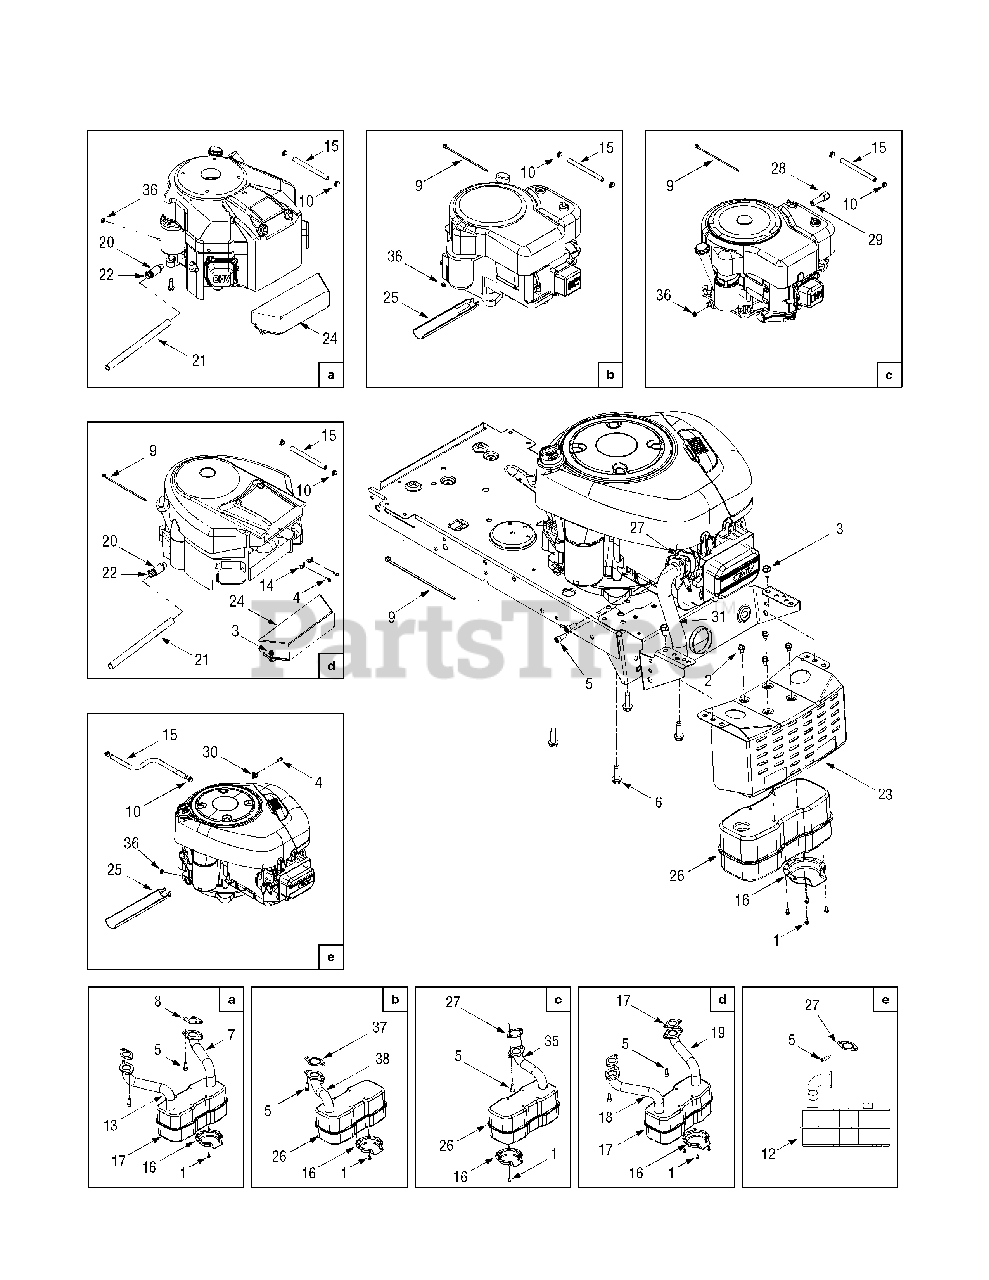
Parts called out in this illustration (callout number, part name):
1	Screw, #8-32, .375
2	Self-tapping Screw, 1/4-14, .625
3	Self-tapping Screw, 5/16-12, .75
4	Screw, #10-32, .625
5	Socket Cap Screw, 5/16-18, .625
6	Self-tapping Screw, 3/8-16, 1.25
7	LH Exhaust Pipe
8	Exhaust Gasket
9	Cable Tie, 7.4"
10	Hose Clamp, .490
11	Screw, 1/4-20, 0.500
12	Muffler, Exhaust
13	RH Exhaust Pipe
14	Casing Clamp
15	Fuel Line Hose
16	Muffler Deflector
17	Muffler, Twin Inlet
18	RH Exhaust Pipe
19	LH Exhaust Pipe
20	Oil Drain Valve
21	Oil Drain Hose
22	Oil Drain Cap
24	Engine Heat Shield
25	Oil Drain Sleeve
26	Muffer, Single Inlet
27	Exhaust Gasket
28	Oil Drain Cap, 3/8-18
29	Oil Drain Pipe, 3/8-16, 2.0
30	Casing Clamp
31	Exhaust Pipe
32	Screw, #8-18 x .50
33	Hex Screw, 7/16-20, 1.25
34	Belt Keeper Pin, 5/16, 4.75
35	Exhaust Pipe
36	Hex Sems Nut, 1/4-20
37	Exhaust Gasket
38	Exhaust Pipe
